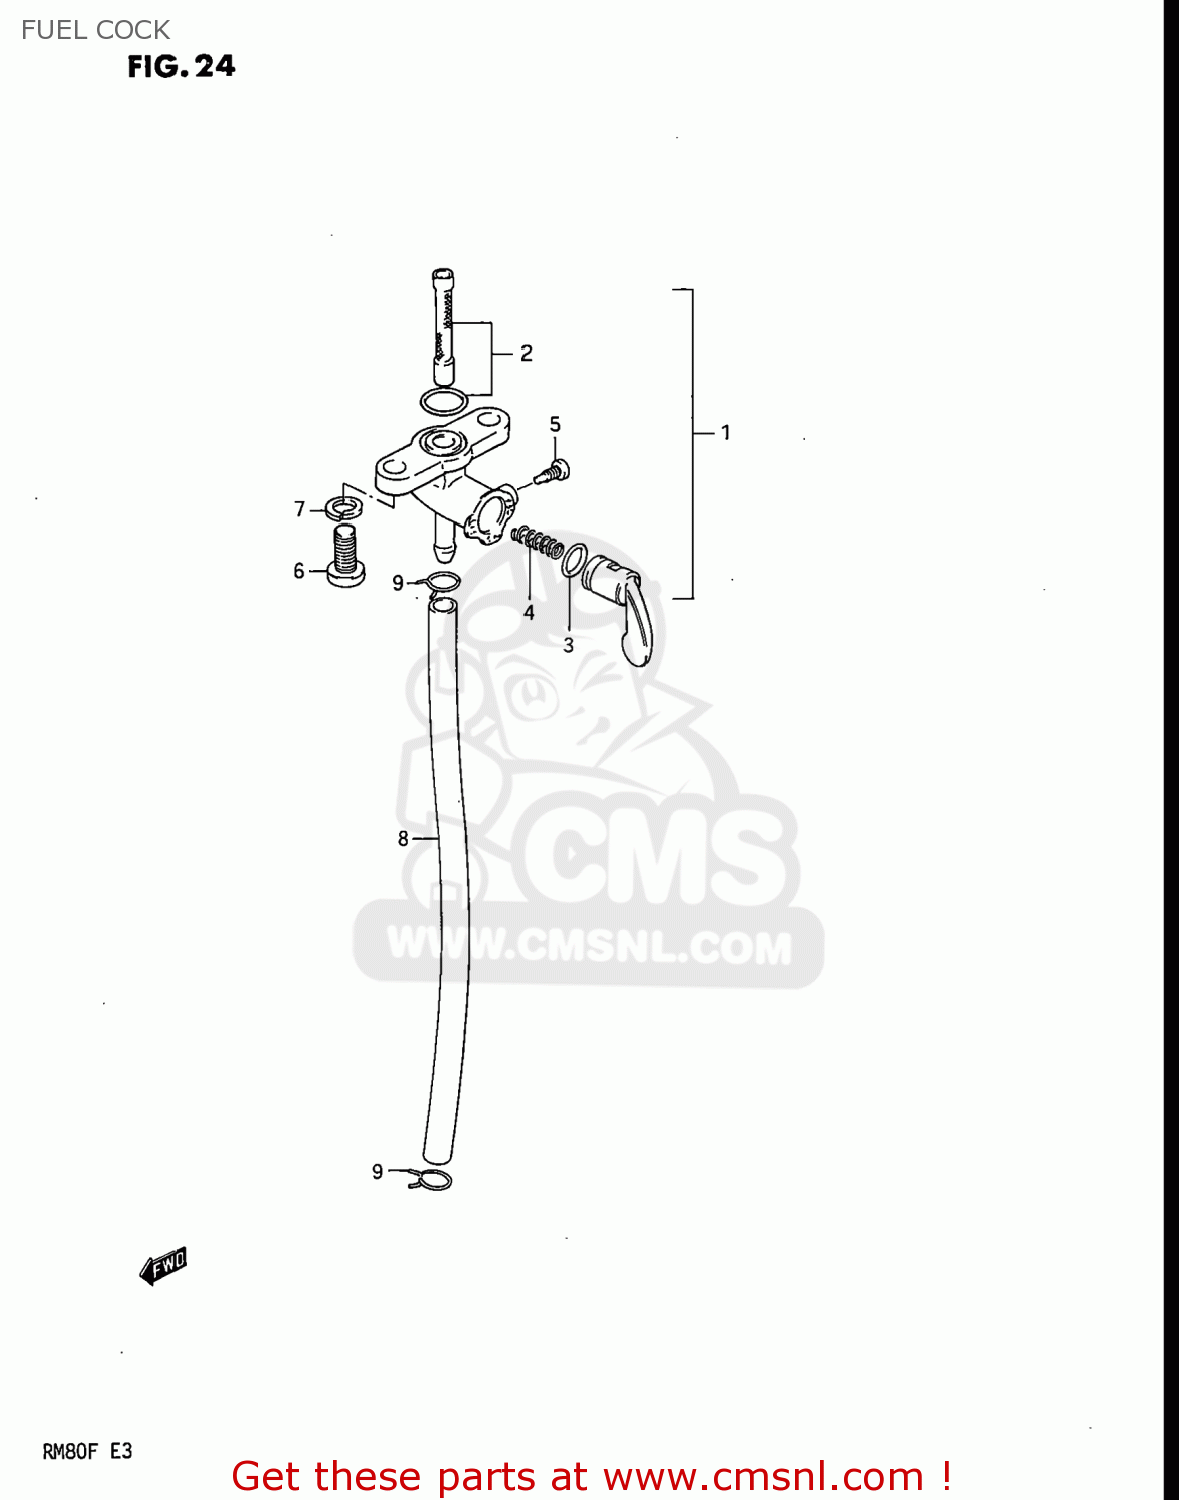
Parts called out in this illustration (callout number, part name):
1	COCK ASSY,FUEL
2	FILTER SET FUEL
3	O RING,LEVER
4	SPRING,FUEL COCK VALUE
5	SCREW
6	SCREW
7	LOCK WASHER
8	HOSE
9	CLIP
